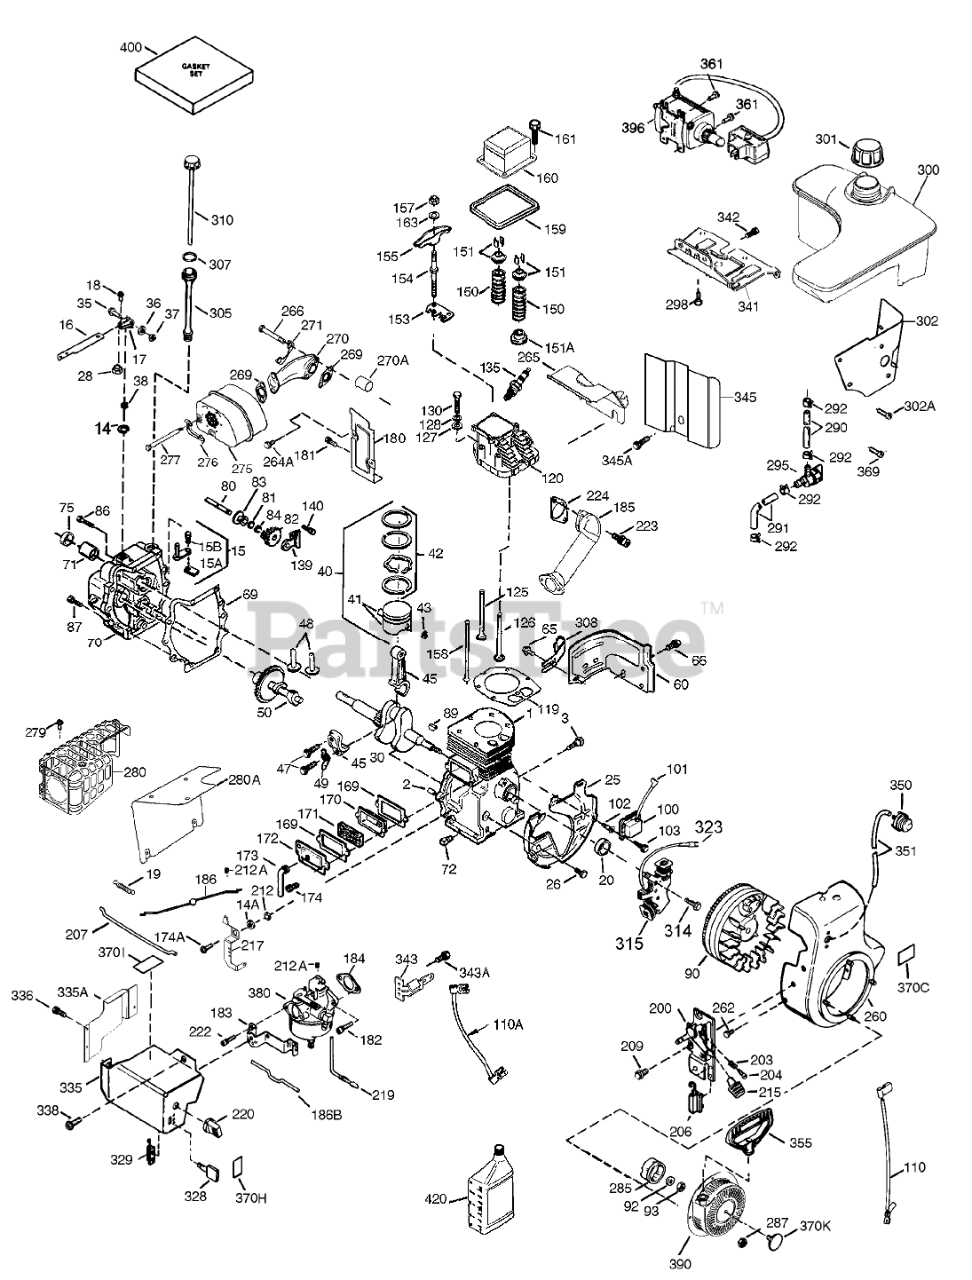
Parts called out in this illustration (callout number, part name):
1	Cylinder (Incl. Ref.# 2, 20, and 72)
2	Pin-Dowel
3	Screw (1/4-20x1/2)
14	Washer-Flat
14A	Washer
15	Governor Rod (Incl. Ref. #15A and 15B)
15A	Yoke-Governor
15B	Screw (6-40x5/16)
16	Lever-Governor
17	Clamp-Lever, Governor
18	Screw (T-15, 8-32x7/16)
19	Spring-Extension
20	Seal-Oil
25	Baffle-Housing, Blower
26	Screw (1/4-20x19/32)
28	Nut-Lock
30	Crankshaft
35	Screw
36	Washer-Lock
37	Nut-Lock
38	Ring-Retaining
40	Piston-Pin and Ring Set (STD)
40	Piston- Pin and Ring Set (.010 O S)
41	Piston & Pin Ass-y (Std.)(Incl. Ref.#43)
41	Piston and Pin ASM (.010)(Incl. Ref.#43)
42	Ring Set (STD)
42	Ring Set (.010 O S)
43	Ring-Retaining, Piston Pin
45	Connecting Rod ASM (Incl. Ref. #47 and 49)
47	Bolt-Rod, Connecting
48	Lifter-Valve
49	Dipper-Oil
50	Camshaft (MCR)
60	Extension-Housing, Blower
65	Screw (10-24 x 9/16)
66	Screw
69	Gasket-Cover, Cylinder
70	Cover-Cylinder (Incl. Ref. #14, 15, 38, 71, 75)
71	Bushing-Crankshaft
72	Plug-Drain, Oil (SQH 1/4-18)
75	Seal-Oil
80	Shaft-Governor
81	Washer-Flat
82	Governor Gear ASM
83	Spool-Governor
84	Ring-Retaining
86	Screw (1/4-20x1-3/16)
87	Screw (1/4-20x1-11/16)
89	Key-Flywheel
90	Flywheel ASM
92	Washer-Belleville
93	Nut-Flywheel
100	Ignition-Solid State
101	Cover-Spark Plug
102	Stud-Mounting, Solid State
103	Screw (T-15, 10-24 x 15/16)
110	Wire-Ground
110A	Wire-Ground
119	Gasket-Head, Cylinder
120	Head-Cylinder (Incl. Ref. #151A)
125	Valve-Exhaust (STD)
125	Valve-Exhaust (1/32)
126	Valve-Intake (STD)
127	Washer-Flat
128	Washer-Belleville
130	Screw (5/16-18 X 2-1/2)
135	Spark Plug-Resistor (R N 4C)
139	Bracket-Gear, Governor
140	Screw (10-24x1/2)
150	Spring-Valve
151	Keeper-Spring, Valve
151A	Cap-Spring, Valve
153	Guide-Rod, Push
154	Stud-Arm, Rocker
155	Arm-Rocker
157	Nut-Jam
158	Rod-Push
159	Gasket-Cover, Rocker Arm
160	Cover-Arm, Rocker
161	Screw
163	Washer
169	Gasket-Cover, Valve
170	Body-Breather
171	Element-Breather
172	Cover-Valve
173	Tube-Breather
174	Screw
174A	Screw (10-24 X 29/32)
180	Extension-Housing, Blower
181	Screw (10-24 x 9/16)
182	Screw (T-30, 1/4-20 X 27-32)
183	Bracket-Choke
184	Gasket-Carburetor To Intake Pipe
185	Pipe-Intake
186	Link-Governor
186B	Spring-Choke
200	Bracket-Control (Incl. Ref. #203, 204 and 206)
203	Spring-Compression
204	Screw (T-10, 5-40x7/16)
206	Terminal
207	Link-Throttle
209	Screw (10-32 x 1/2)
212	Bushing
212A	Bushing
215	Knob-Control
217	Lever-Bellcrank
219	Rod-Choke
220	Knob-Control
222	Screw (10-32 x 1/2)
223	Screw (T-30, 5/16-18 X 7/8)
224	Gasket-Pipe
260	Housing-Blower
262	Screw
264A	Screw (1/4-20 X 5/8)
265	Cover-Head, Cylinder
266	Screw (5/16-18 X 1-9/32)
269	Gasket-Manifold, Exhaust
270	Manifold, Exhaust
270A	Liner-Port, Exhaust
271	Plate-Locking
275	Muffler
276	Plate-Locking
277	Screw (5/16-18 X 4-1/2)
279	Screw
280	Shield-Heat
285	Cup-Starter
287	Nut and Lock Washer (1/4-28)
290	Line-Fuel
291	Line-Fuel (8.62)
292	Clamp-Line, Fuel
295	Valve-Shut Off, Fuel
298	Screw (1/4-15x7/8)
300	Fuel Tank (Incl. 292 and 301)
301	Cap-Fuel
302	Extension-Tank, Fuel
302A	Screw (10-32 x 1/2)
305	Tube-Fill, Oil
307	O-Ring
308	Clip-Tube, Fill
310	Dipstick
314	Screw (1/4-20 x 3/4)
315	Coil-Alternator, 18 Watt (Incl. Ref. #323)
323	Terminal
328	Key-Ignition
329	Terminal
335	Spring
335A	Cover-Carburetor
336	Screw (10-32 x 1/2)
338	Screw (10-32 x 1/2)
341	Bracket-Tank, Fuel
342	Screw (5/16-18 X 7/8)
343	Bracket-Switch, Key
343A	Screw (8-32 x 23/64)
345	Baffle-Heat
345A	Screw (10-32 x 1/2)
350	Primer ASM
351	Line-Primer
355	Handle-Starter, Mitten Grip
361	Screw (T-30, 1/4-20x15/32)
369	Screw (12-16 x 5/8)
370C	Decal-Primer, International Symbol
370H	Decal-Choke
370I	Decal-Warning (Bilingual)
370K	Decal-Tecumseh Logo for Top of Recoil Starter
380	Carburetor (Incl. Ref. #184)
390	Starter-Rewind
396	Starter-Electric (110 Volt)
400	Gasket Set
420	Oil-Engine, S A E 5W30
